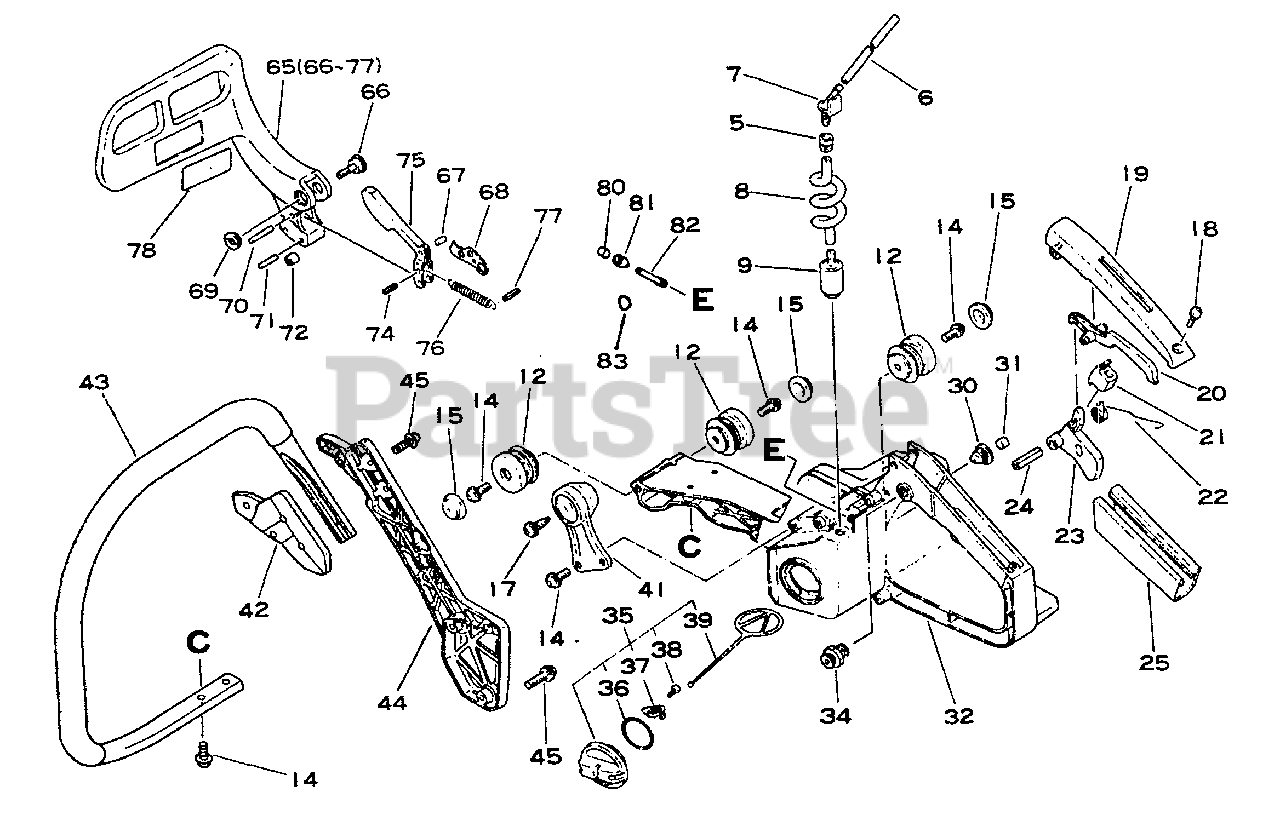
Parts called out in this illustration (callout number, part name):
5	GROMMET
6	PIPE, FUEL - 3×6×100
7	CONNECTOR, PIPE
8	PIPE, FUEL
9	FILTER, FUEL
12	CUSHION
14	SCREW - 5×14
15	CAP, CUSHION
17	SCREW - 5×14
18	SCREW - 4×14
19	COVER, HANDLE
20	CONTROL, THROTTLE
21	CUSHION, THROTTLE
22	SPRING, THROTTLE RETURN
23	TRIGGER, THROTTLE - BLACK
24	PIN, SPRING
25	GRIP, HANDLE
30	VENT ASSY
31	FILTER, CHECK VALVE
32	HANDLE - REAR
34	LATCH, THROTTLE
35	CAP ASSY
36	O-RING 29
37	RETAINER, CONNECTOR
38	SCREW 3×8
39	CONNECTOR, CAP L= 60 MM
41	CUSHION
42	BRACKET, HANDLE - INNER
43	HANDLE, FRONT
44	BRACKET, HANDLE - OUTER
45	SCREW - 5×20
65	BRAKE LEVER ASSY
67	PIN, LOCATING 4×8
68	STOPPER
70	PIN 3×24
71	PIN 3×18
72	SPACER
74	PIN, SPRING 3×12
75	WEIGHT, BRAKE
76	SPRING, RETURN
77	PIN, SPRING
80	VENT ASSY
81	HOLDER, VENT
82	PIPE, VENT
